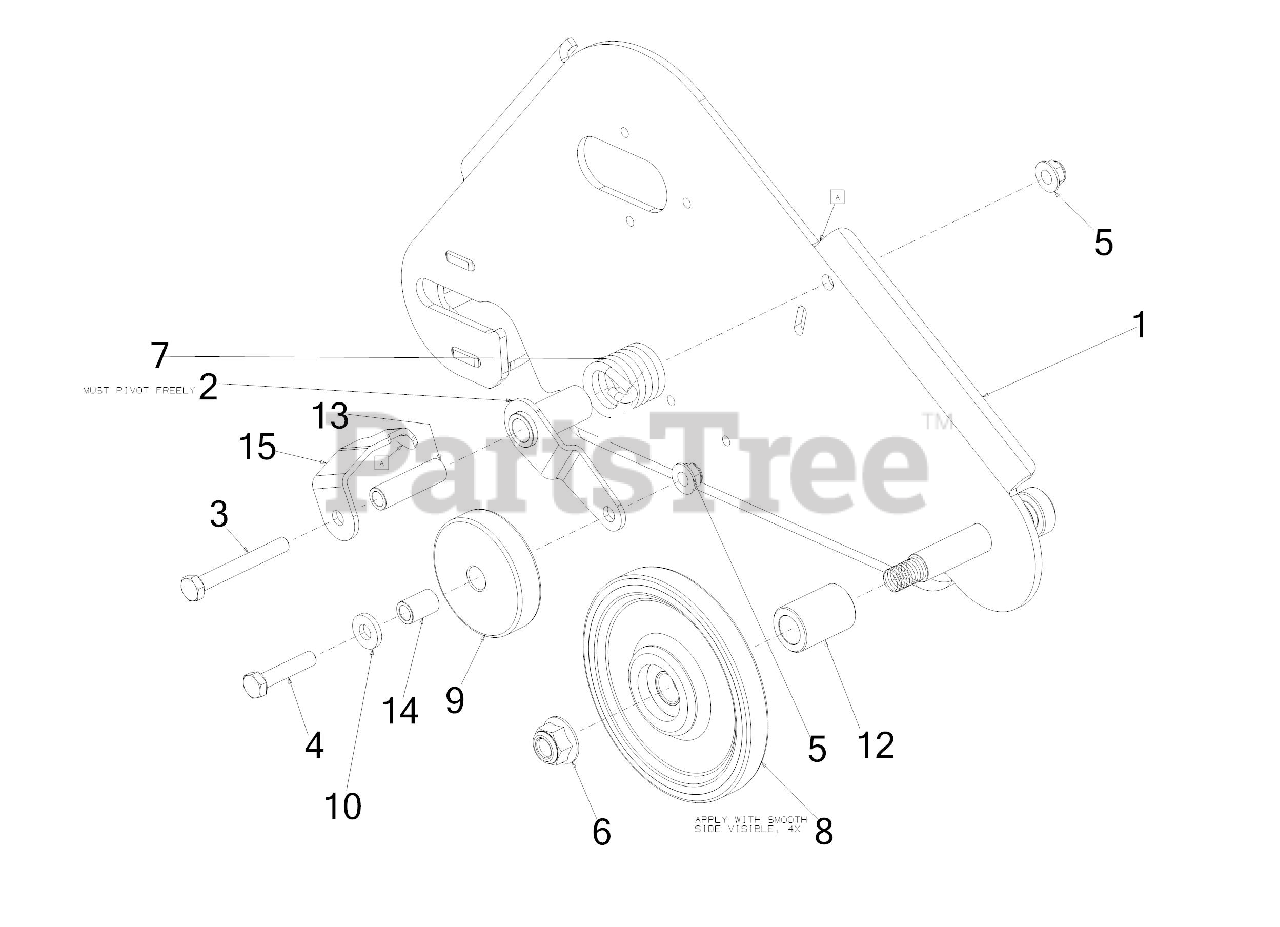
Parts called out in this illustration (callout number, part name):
1	PLATE ASSEMBLY-TRACK (RH)
2	TENSION BRACKET
3	SCREW 5/16-18 x 2.5 GR 5
4	SCREW 5/16-18 x 1.5 LG
5	FLANGE LOCK NUT 5/16-18
7	TORSION SPRING
8	WHEEL-5.00 OD BB
9	WHEEL-TRACK TENSION
10	FLAT WASHER
13	SLEEVE .33X.50X1.73 LG
14	SLEEVE .33X.50X.75 LG
